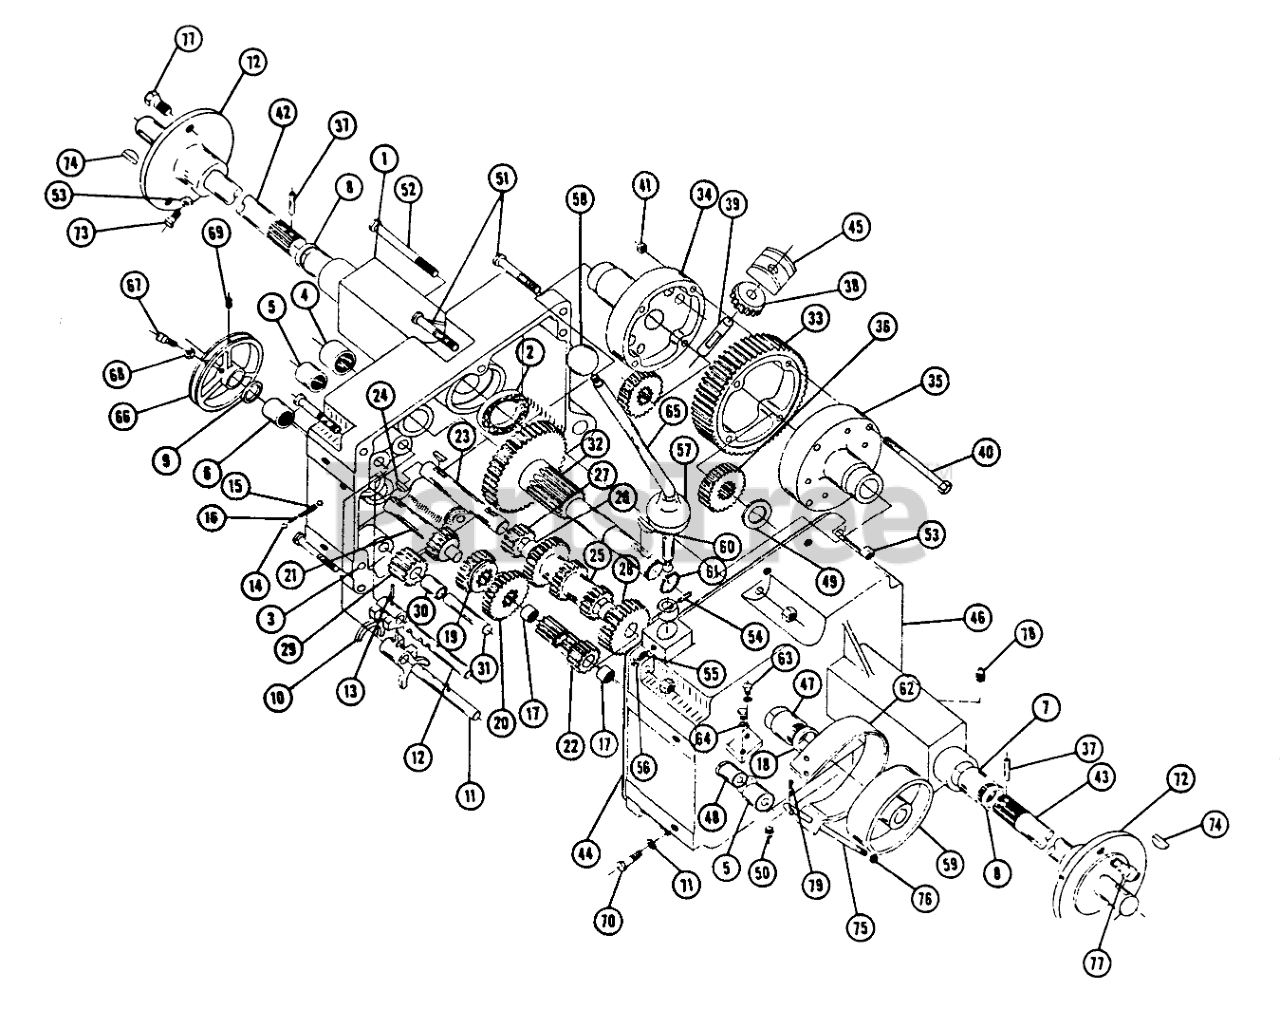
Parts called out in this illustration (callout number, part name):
3	PIN-DOWEL
4	BEARING-NEEDLE
5	BEARING-NEEDLE
10	FORK-SHIFT
13	PIN-ROLL
14	BALL-DETENT
17	BEARING-NEEDLE
19	GEAR-HI AND 2ND
20	GEAR-LOW AND REVERSE
24	Key
26	BUSHING-BRONZE
28	GEAR-CLUSTER SHAFT
29	GEAR/BUSHING ASM-REVERSE IDLER
30	BUSHING
31	PIN-DIFFERENTIAL
33	GEAR DIFF BULL
34	DIFF CASE RH
40	Bolt - Hex 3 3/8 16 x 4
41	Nut-Hex Lock 3/8-16
42	Clevis
44	GASKET-TRANSMISSION
45	BLOCK
50	Plug 3/8 Pipe
51	Bolt, 3/8 16 x 2
52	Bolt Hex 3/8-16 x 1
53	Nut 1/4-20 Nylok
54	Roll Pin
55	Set Screw Nylok 1/4-20 x 3/4
56	Nut-Nylok
57	COVER-DUST
60	KEY-WOODRUFF
61	Snap Ring 1" Shaft
63	Bolt - Hex 1/4-20 x 5/8
64	Lock Washer 1/4 Dia.
65	Ass-y. Shift Stick
67	Set Screw Sq. Hd. 5/16-18 x
68	Nut 5/16-18 Jam
69	Set Screw 5/16-18 x 5/16
70	Bolt 3/8-16 x 1
71	Lockwasher
73	Set Screw-3/8-16 x 1
75	Rod
76	Nut 3/-16 Elastic Stop
77	BOLT-LUG, WHEEL
78	Plug 1/4 Pipe
79	Hairpin
